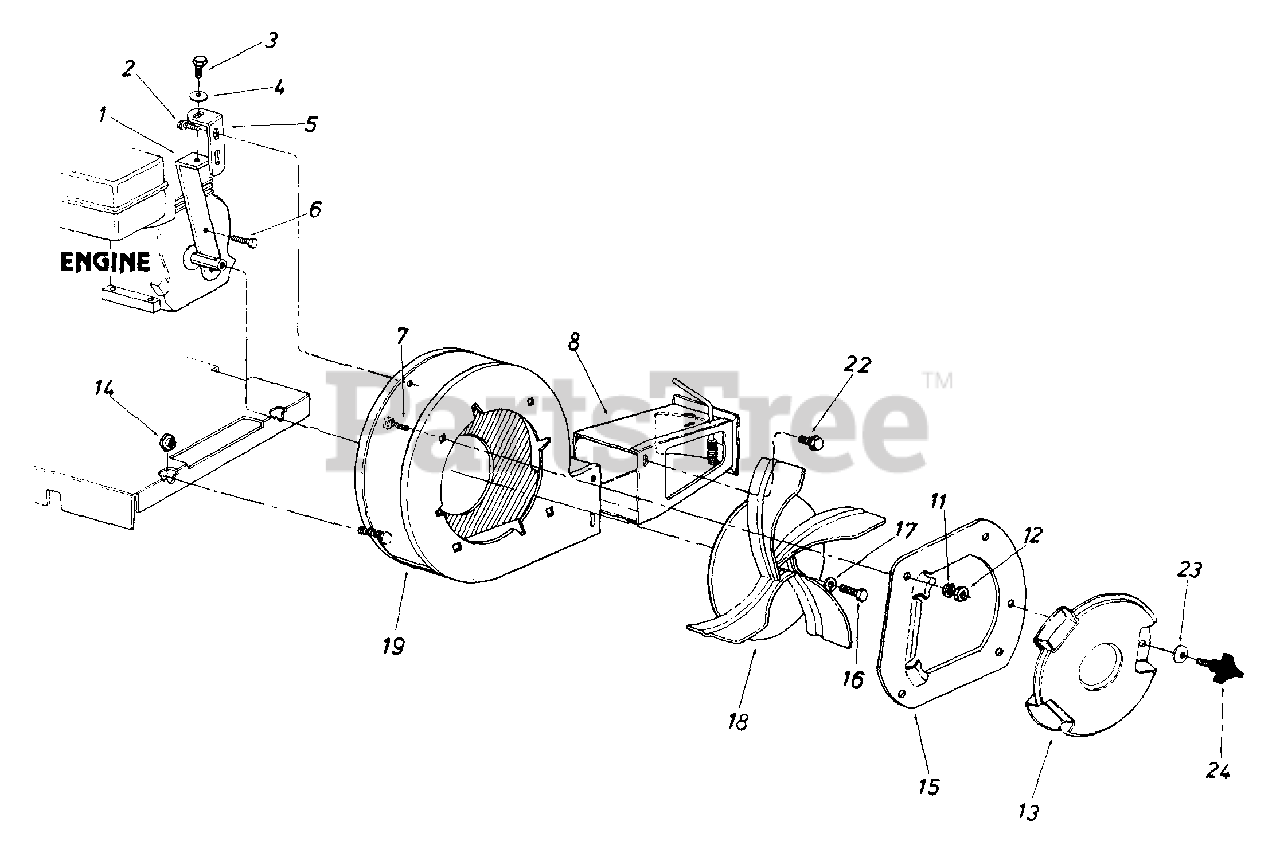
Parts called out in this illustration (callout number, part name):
3	Hex Bolt 5/16-18 x .75" Lg.
4	L-Wash. 5/16" I.D.
7	Carriage Bolt 5/16-18 x .62"
12	Hex Nut 5/16-18 Thd.
13	Blower Guard
14	Hex Shoulder Nut .50" I.D.
15	Nozzle Plate Ass'y.
16	Hex Bolt 3/8-24 x 1.25"
17	L-Wash. 3/8" I.D. H.D.
23	Bell-Wash..34" I.D. x .87" O.D.
24	3-Arm Thumb Scr. 5/16-18 x .75" Lg.
